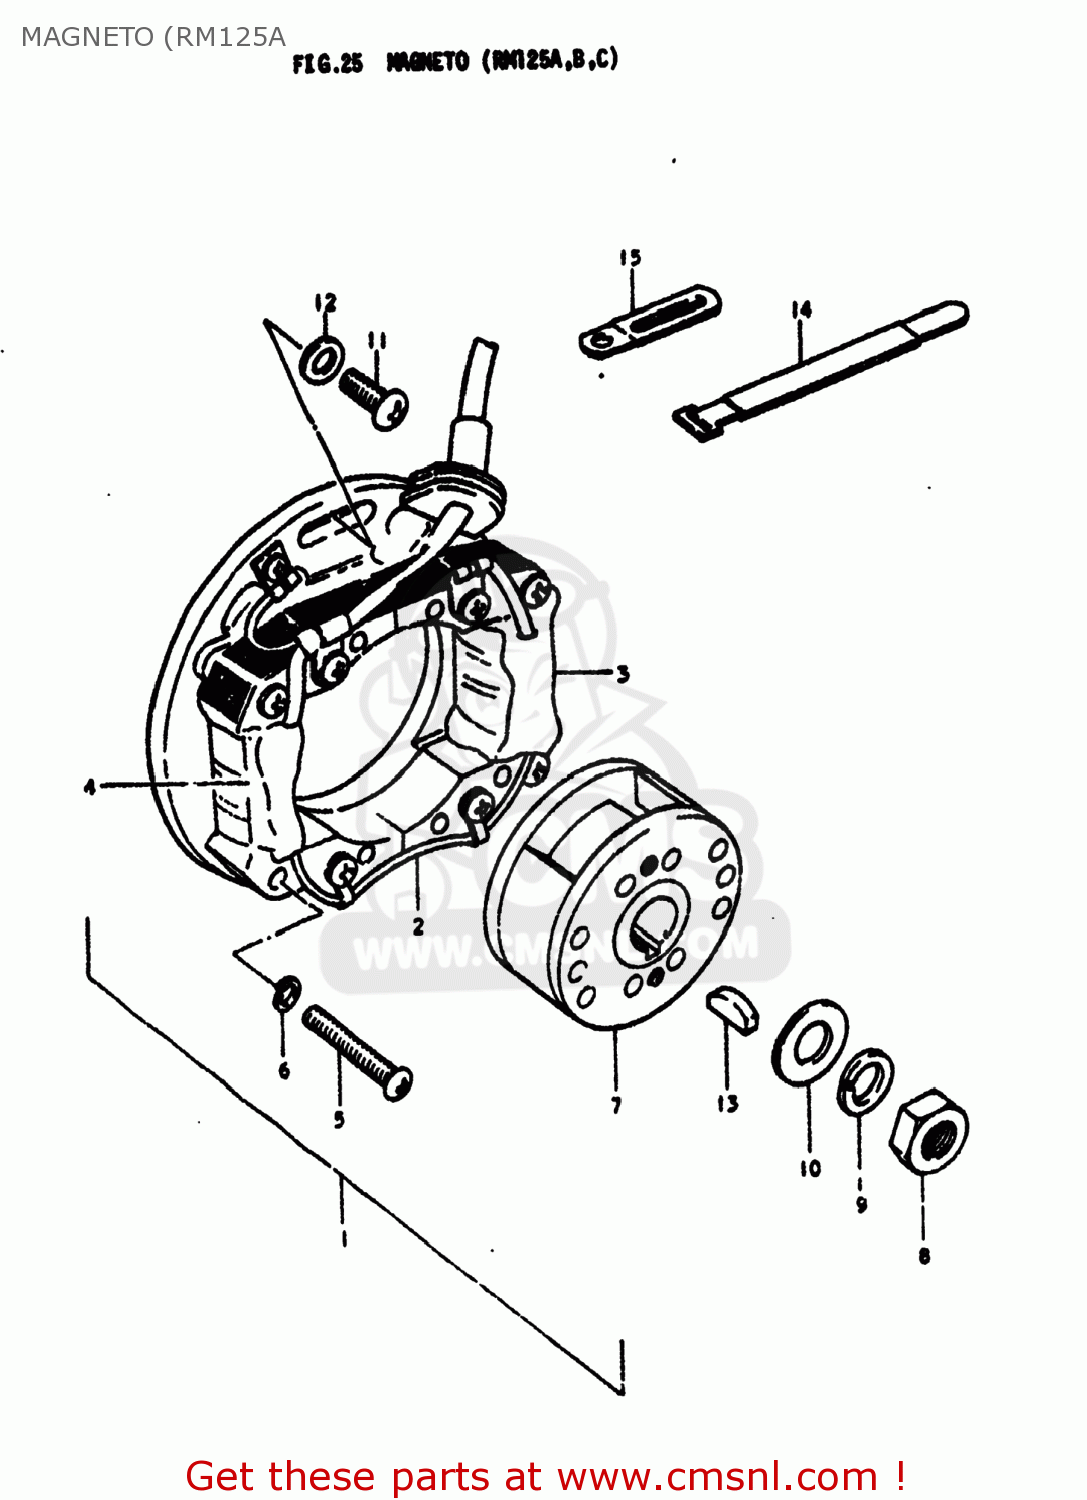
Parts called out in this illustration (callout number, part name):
1	MAGNETO ASSEMBLY
2	STATOR ASSEMBLY
3	COIL,PRIMARY
4	COIL,PULSER
5	SCREW
6	LOCK WASHER
7	ROTOR ASSEMBLY
8	NUT (10MM)
9	LOCK WASHER
10	WASHER
11	SCREW
12	WASHER
13	KEY 4MM
14	CLAMP
15	CLAMP
